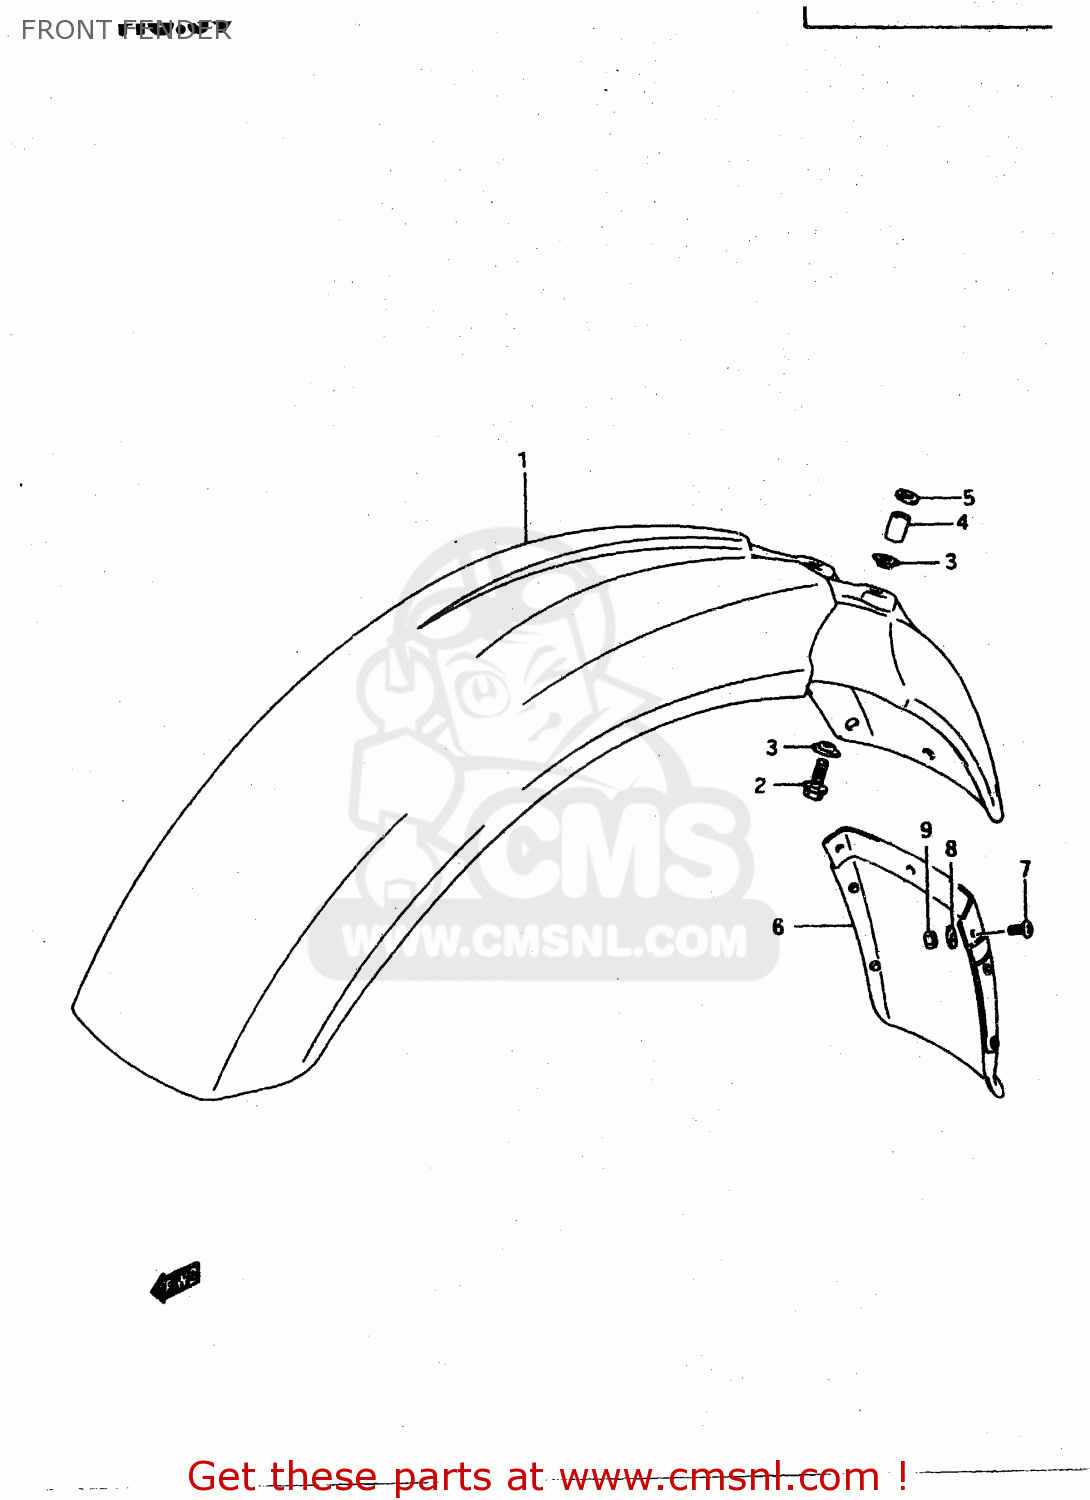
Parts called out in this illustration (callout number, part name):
1	FENDER,FR
2	BOLT
3	WASHER
4	SPACER (6.8X10X16)
5	WASHER
6	MUD GUARD, FRONT FENDER
7	SCREW
8	WASHER(5.5X16X1.2)
9	NUT
